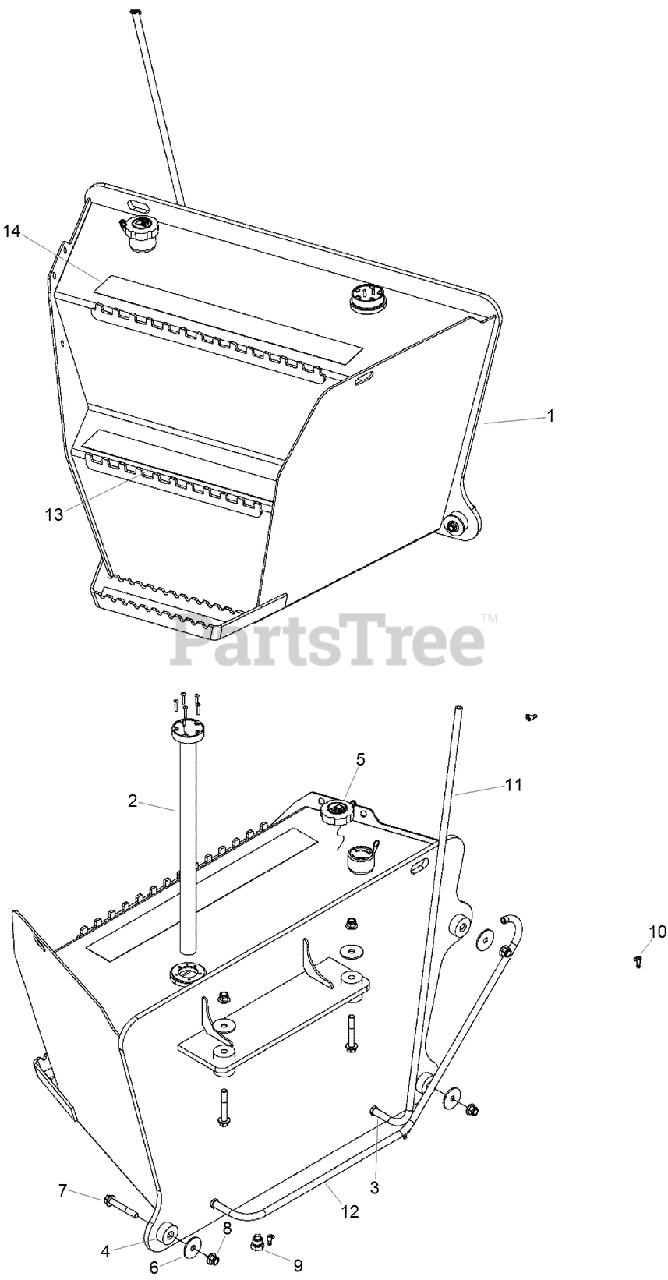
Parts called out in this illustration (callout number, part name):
1	Weldment - Fuel Tank
2	SENDER-FUEL
3	FITTING-STRAIGHT
4	ISOLATOR-MOUNTING, UNIVERSAL
5	CAP-DIESEL FUEL W/ LOCK
6	WASHER-FLAT
7	SCREW-HHF
8	NUT-HHF, LOCK
9	PLUG-HEX, MAGNETIC
10	CLAMP-Hose Type M #04
11	HOSE-Fuel Tank
12	HOSE-Fuel Tank
13	TAPE-ANTI SKID, LOWER STEP
14	STRIP-ANTI SKID
